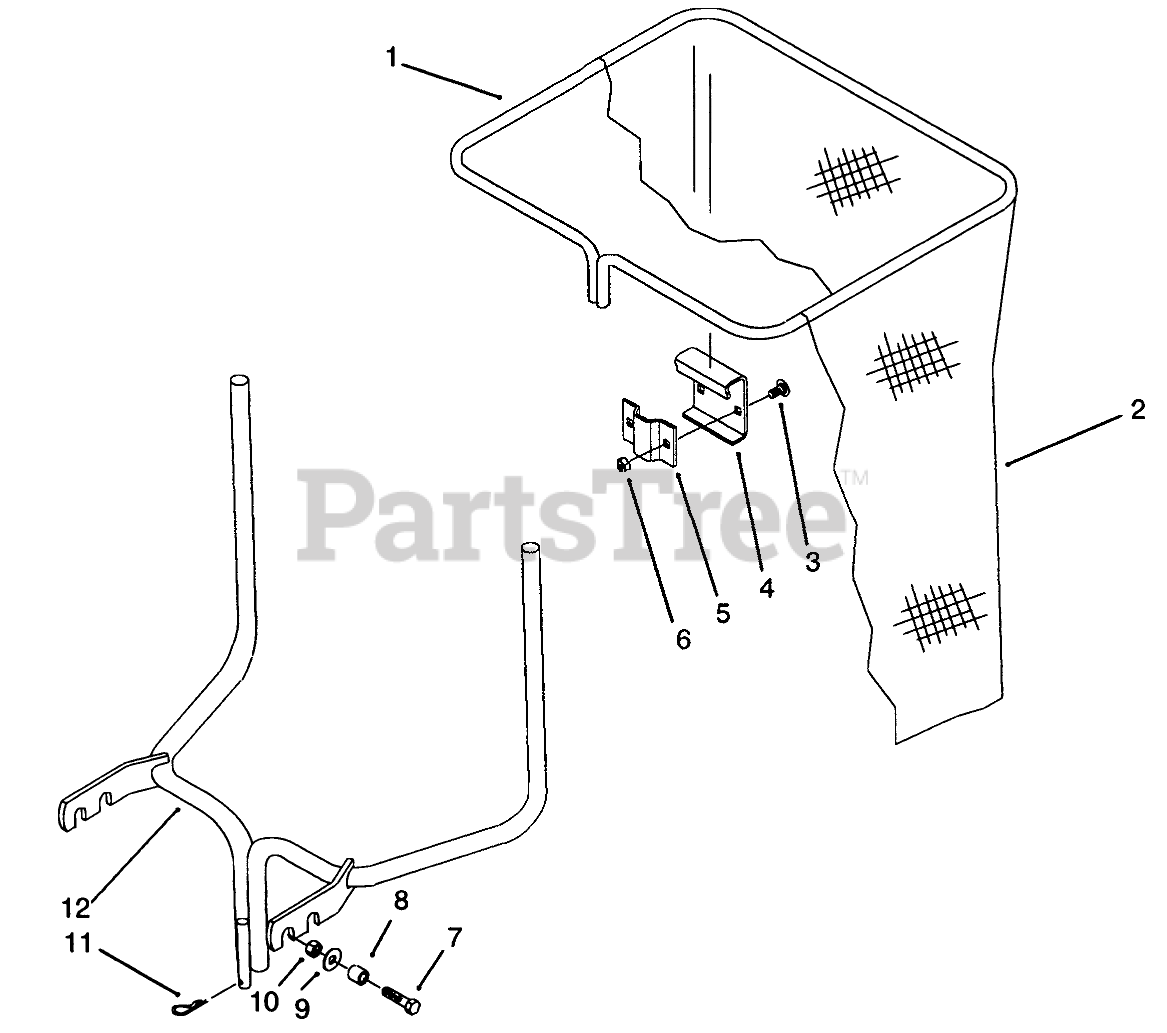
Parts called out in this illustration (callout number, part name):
1	Bag Frame
2	Bag
3	BOLT-CARR
4	Bag Hanger
5	Clamp
6	NUT-LOCK, NI
7	SCREW-HH
8	SPACER
9	WASHER
10	NUT-LOCK, NI
11	Hairpin
12	Bracket-Quick Attach
